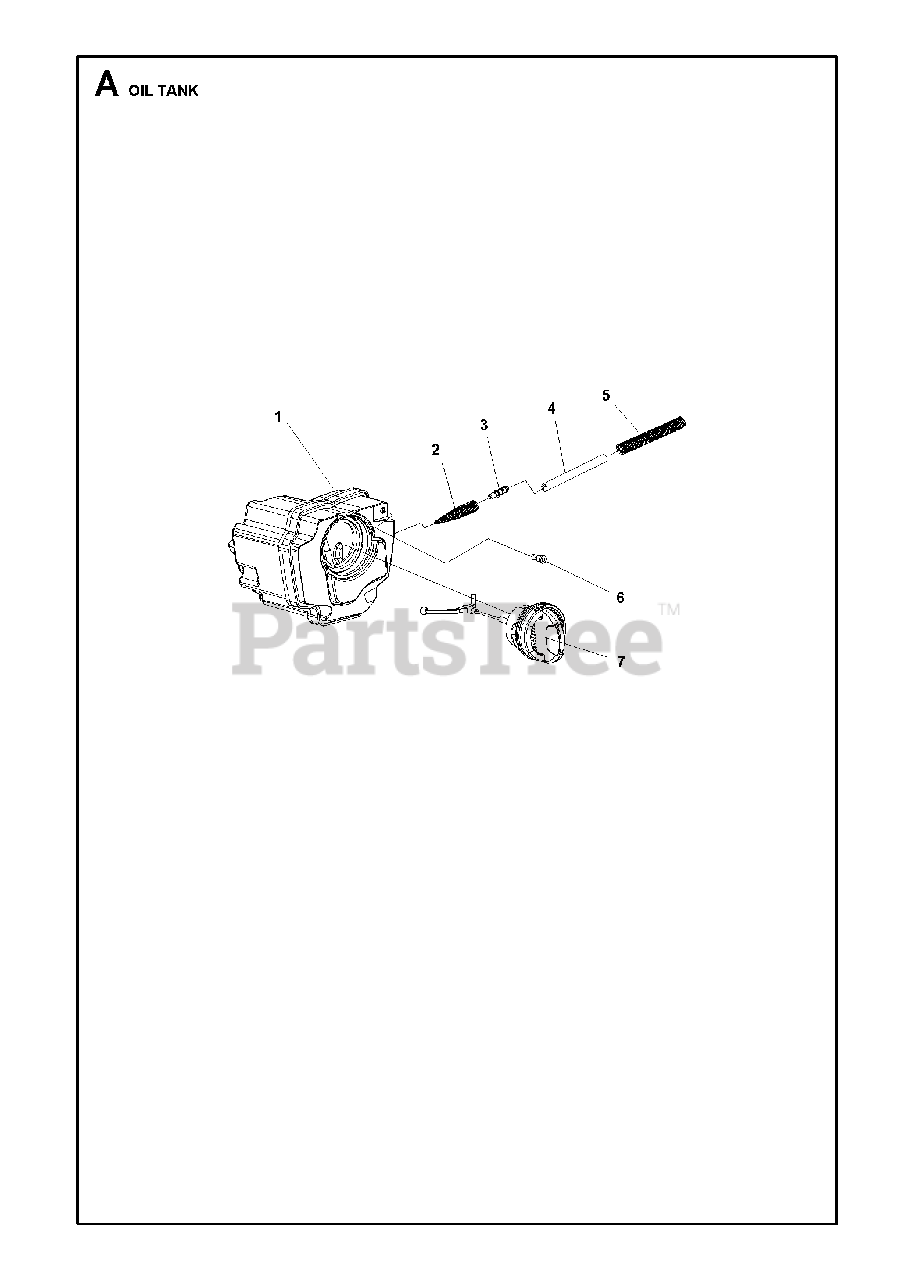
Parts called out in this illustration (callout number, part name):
2	Spring, Filter
4	OIL HOSE WHITE AND TRANSPAREN
5	SPRING PIN SPRING, OIL HOSE S
6	VALVE, FUEL INLET
7	TANK CAP ASSY
